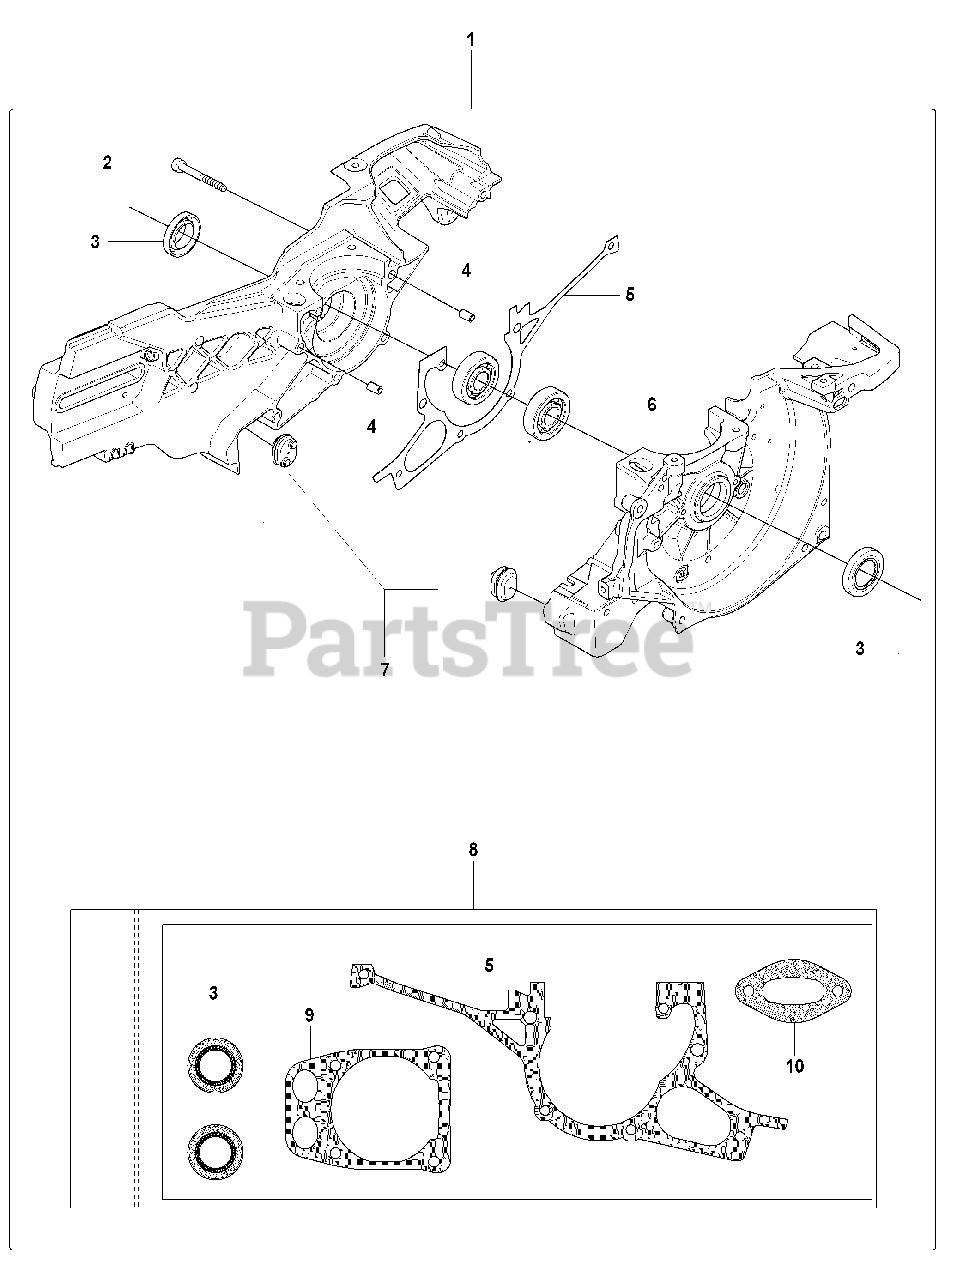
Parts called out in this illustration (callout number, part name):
1	CRANKCASE ASSY
3	SEALING RING
4	GUIDE BUSHING
6	BALL BEARING
7	RUBBER BUSHING
8	GASKET KIT
9	GASKET
10	GASKET MUFFLER
